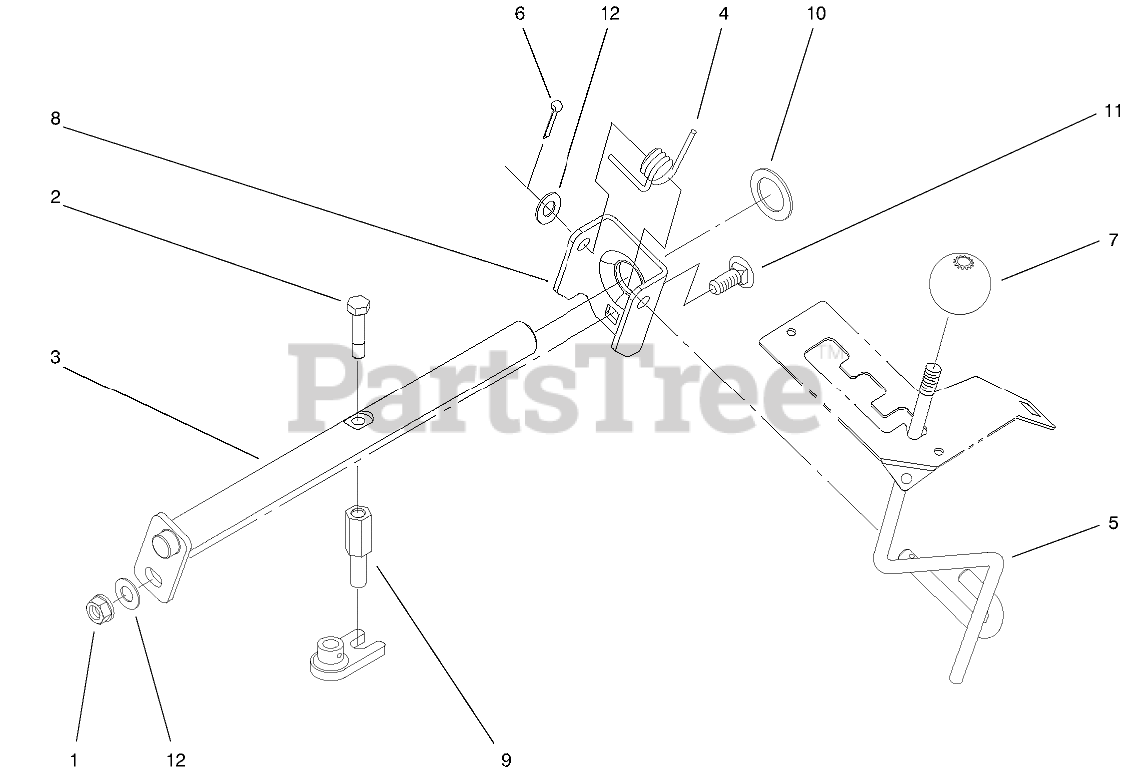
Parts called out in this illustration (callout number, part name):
1	NUT-LOCK, NI
2	SCREW-THREAD LOCKING
3	SHIFT ROD ASM
4	SPRING-TORSION
5	LEVER-SHIFT
6	PIN-COTTER
7	KNOB-HI / LO SHIFT
8	BRACKET-PIVOT
9	ROD-PIVOT, SHIFT
10	SPACER
11	SCREW-CARR
12	WASHER-FLAT
